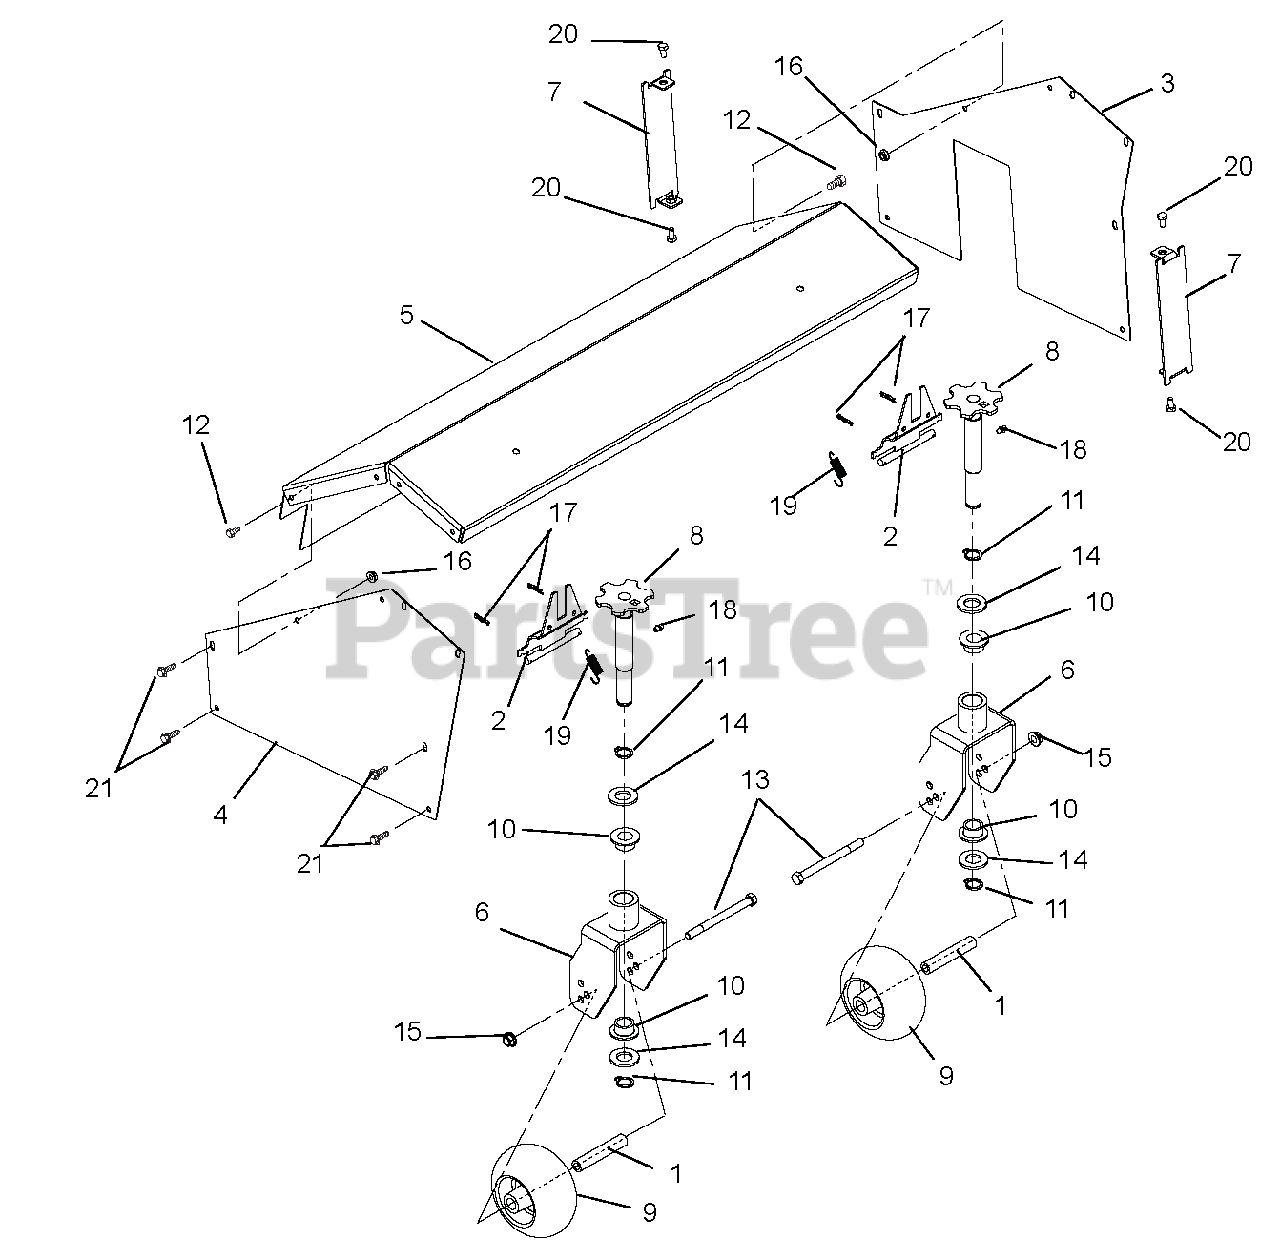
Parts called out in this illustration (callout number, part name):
1	SPACER, CASTER WHEEL
2	LOCK,CASTER HEIGHT
3	COVER,LH SIDE BRUSH
4	COVER,RH SIDE BRUSH
5	COVER WITH DECALS, 28"BRUSH
6	CASTER FORK, BRUSH
7	COVER,END
8	HEIGHT ADJUSTER, CASTER
9	WHEEL, ANTI SCALP
10	BSHG-FLG .762X1.0X.580X1.48 NY
11	RG-RTNG-EXT .689X.078
12	@BLT-HEX .25-20X.50 GR5 YWZC
13	@BLT-HEX .38-16X4.50 GR5 YWZC
14	@WSHR-FL-STL.812X1.50X.135YWZC
15	@NUT-LK-TOP-FLG .38-16 YWZC
16	@NUT-LK-TOP-FLG .25-20 YWZC
17	PIN-HAIR, ENDRIES #25 YWZC
18	FTG-LUBE .25-28X.256 YWZC
19	SPRING-EXT .047 X .438 X 1.85
20	@BLT-HEX .25-20X.50 GR5 YWZC
21	SCR-TAP .25-20X.50 HWH TR YWZ
